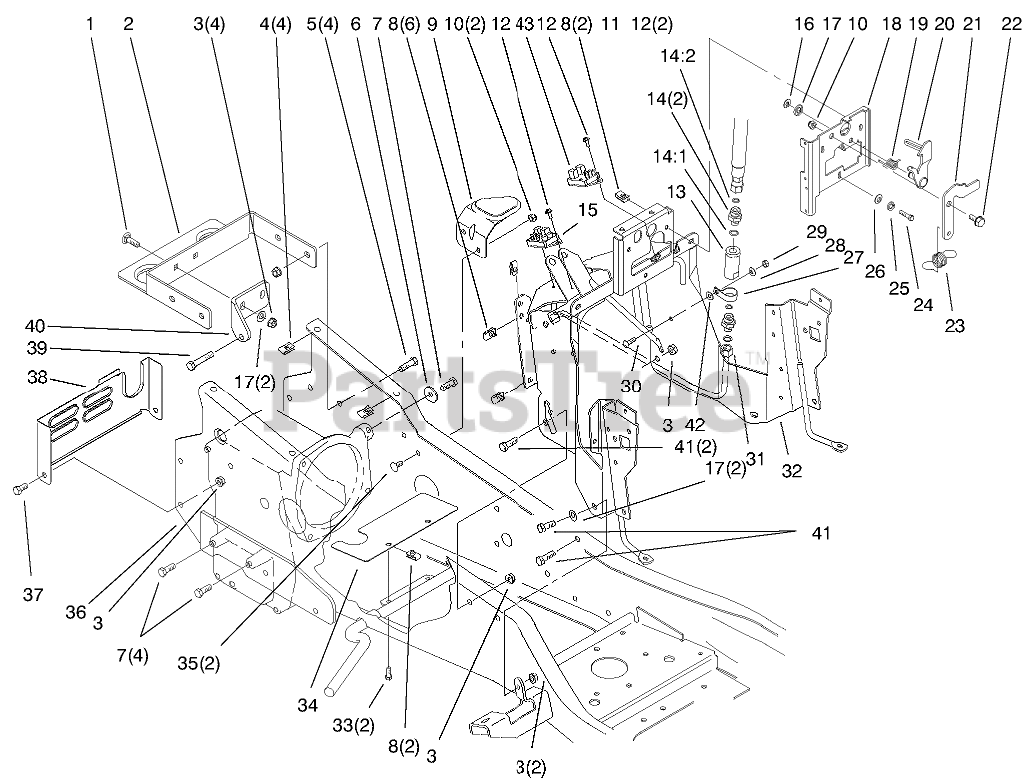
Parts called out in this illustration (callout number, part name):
1	BOLT-CARR
2	Support-Gas Tank
3	NUT-LOCK, NI
4	NUT-U
5	SCREW-HH
6	WASHER
7	SCREW-HH, LOCK
9	SUPPORT-TANK, FUEL
10	NUT-LOCK, NI
11	MODULE-LOW FUEL
12	SCREW
13	FILTER-SCREEN, HYD
14	FITTING-HYD. STRAIGHT
14:1	O-RING
14:2	O-RING
15	MODULE-CRUISE
16	RING-RETAINING
17	WASHER-FLAT
18	BRACKET-LATCH
19	SPRING-LEVER, LATCH
20	LEVER-LATCH
21	LATCH-LEVER, TENSION
22	BOLT-SHOULDER
23	SPRING-LEVER, LATCH
24	SCREW-HH
25	WASHER-LOCK
26	WASHER-FLAT
27	CLAMP-R
28	WASHER-FLAT
29	NUT-LOCK, NI
30	BOLT-CARR
31	TUBE-HYD
32	TOWER ASM
33	SCREW-HH
34	BAFFLE-FAN
35	SCREW-CARR
37	SCREW-HH
38	COVER-REAR
39	SCREW-HH W/LOCTITE
40	Strap-Torque
41	SCREW-HH
42	PUSHNUT-RETAINER, BOLT
43	MODULE-CLUTCH
